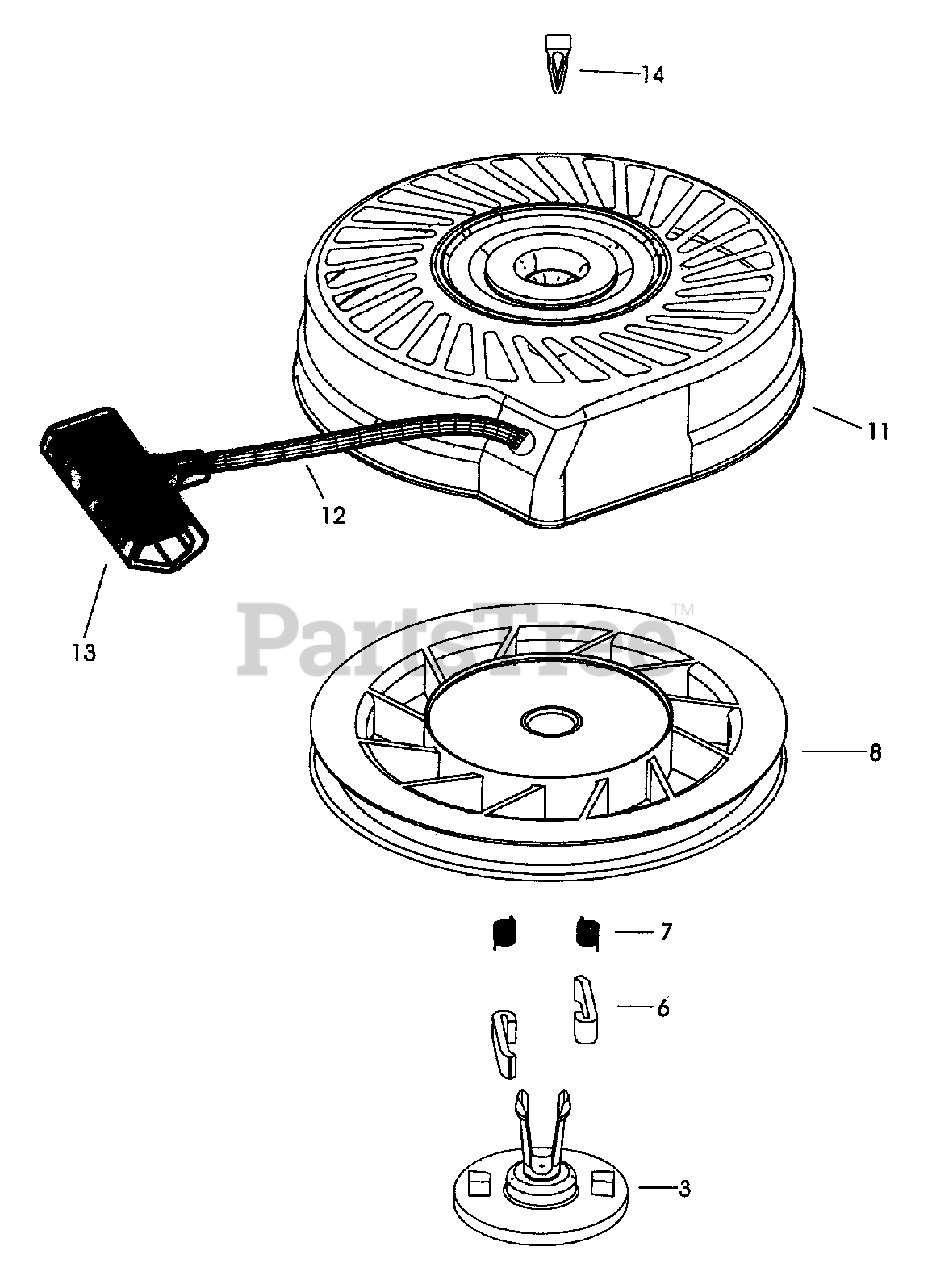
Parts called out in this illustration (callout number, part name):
3	Retainer
6	Starter Dog
7	Dog Spring
8	Pulley & Rewind Spring ASM
11	Starter Housing ASM (40 degree grommet)
12	Starter Rope (Length 98" x 9/64" dia.)
13	Starter Handle
14	Locking Tab
